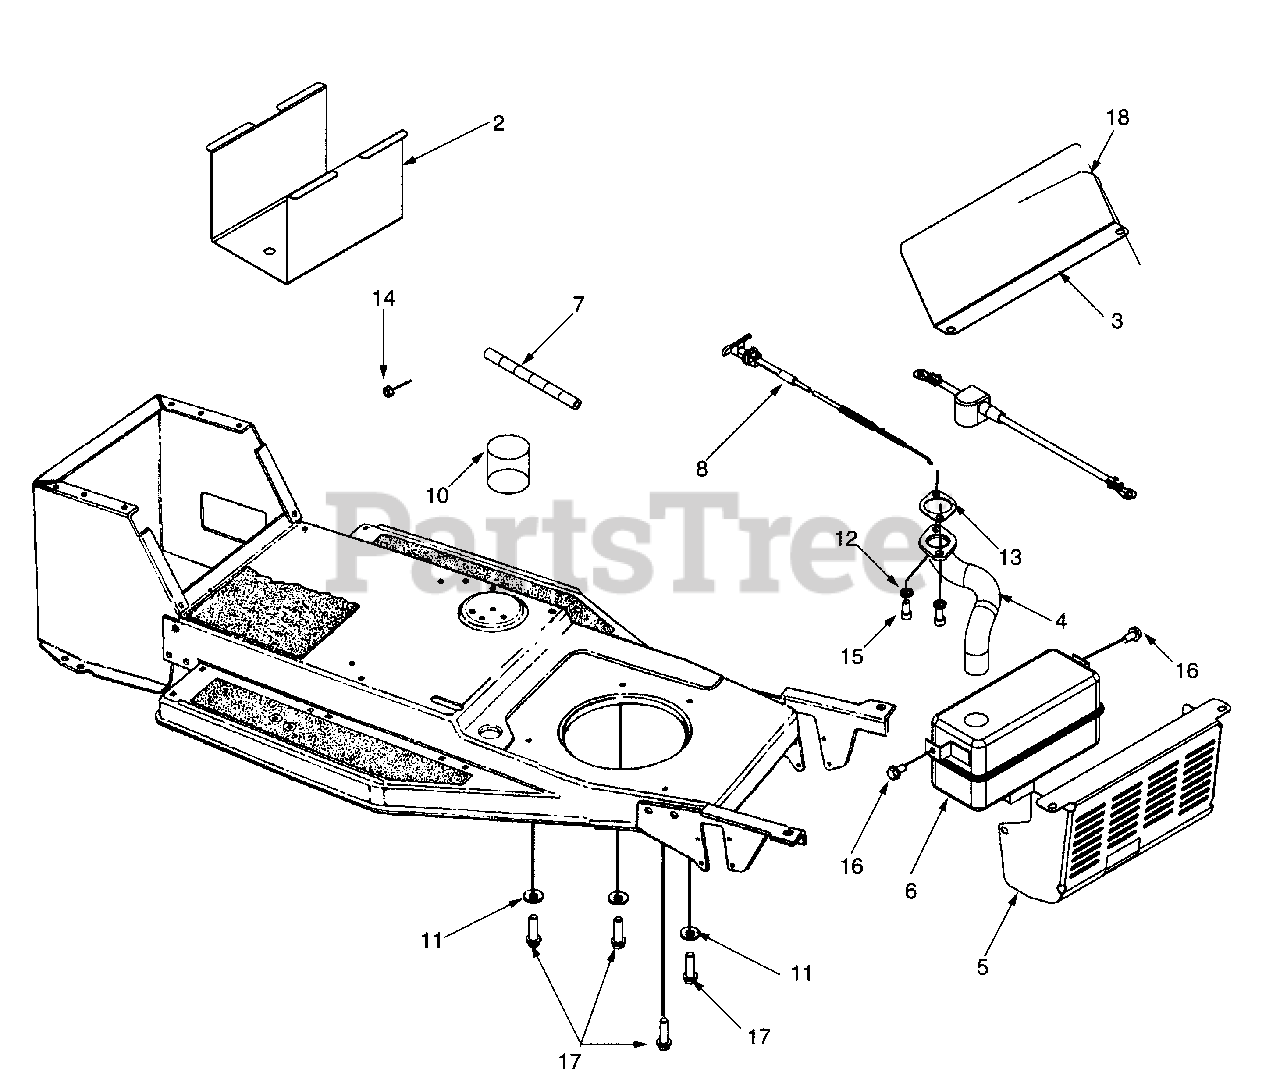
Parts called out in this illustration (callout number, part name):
4	Pipe Muffler
7	Fuel Line hose
8	Choke Control
10	SAE 30W Motor Oil
11	Flat Washer .38 I.D. x .93 O.D. x .110
12	Lock Washer 5/16
13	Gasket, Exhaust
14	Hex Nut 1/4-20
15	Socket Head Screw 5/16-18 x .625
16	Hex Wash. Head TT Screw 5/16-18 x .62
17	Hex Wash Hd. Self-Tapping Screw 3/8-16 x 1.25
18	Wire Assembly #6 x 14 Lg. Red w/Boot
